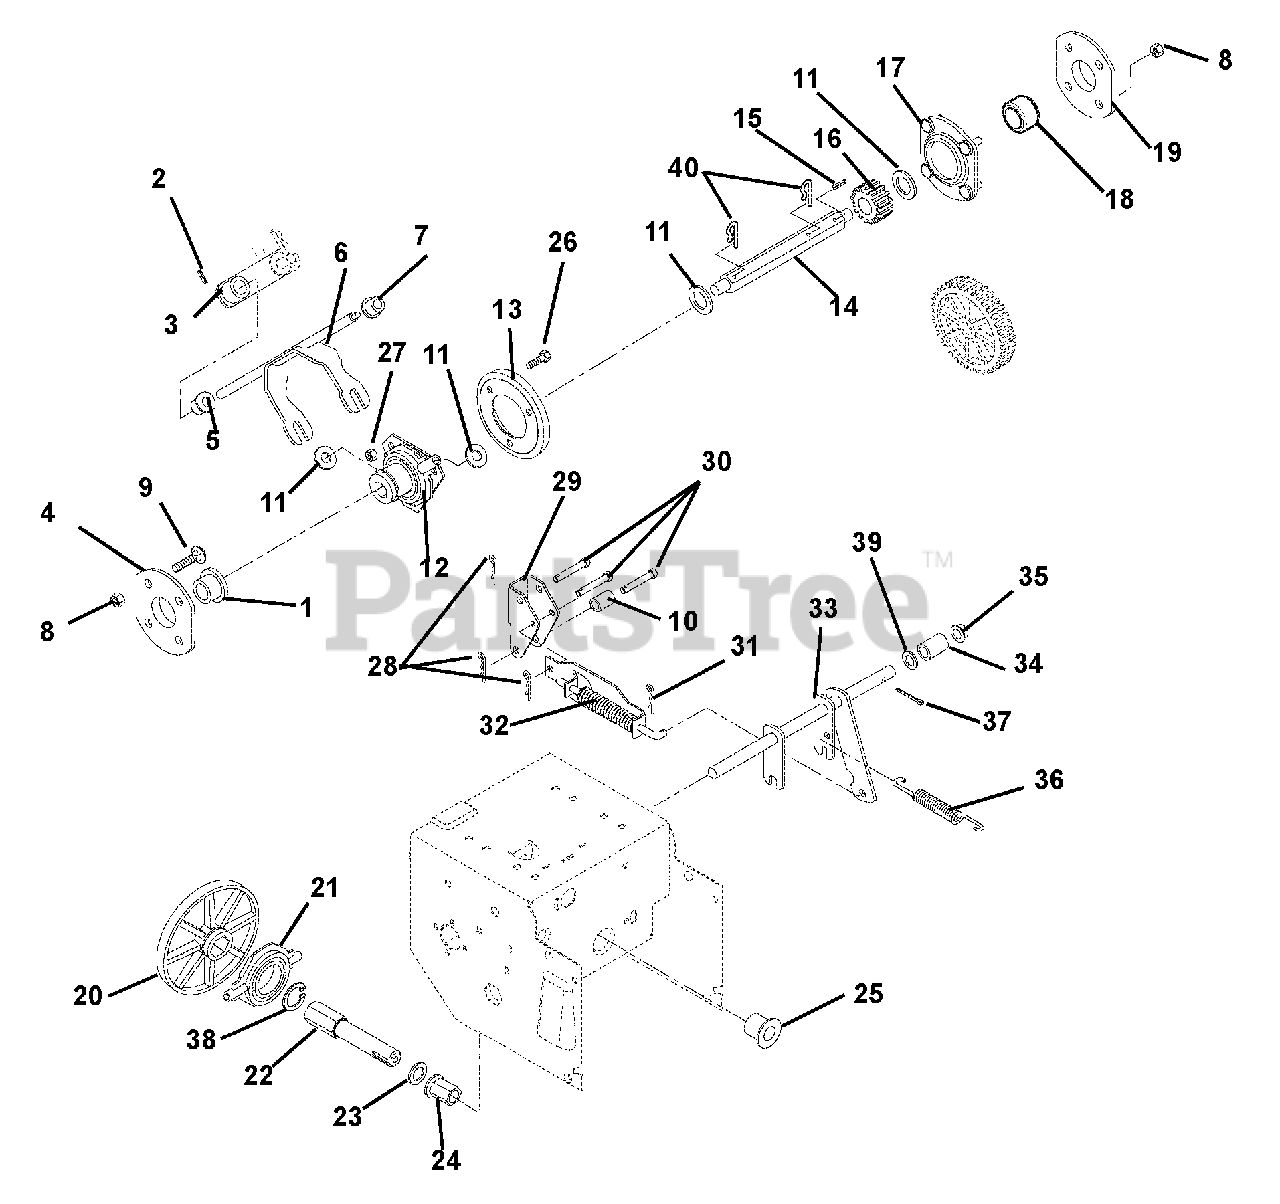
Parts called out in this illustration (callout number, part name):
1	BSHG-FLG .500X.750X.625X.937
2	PIN-ROLL .156X.88
3	WELDMENT, SPEED CONTROL ARM
4	FLANGE AND BUSHING
5	BSHG-FLG .500X.625X.500X.750
6	FORK-SPEED
7	BSHG-FLG .325X.444X.440X.560
8	NUT-LK-DUAL FACE 10-24 YWZC
9	BLT-RDHDSQSHK #10-24X.38 GR2YW
10	SPACER .325 X.625 X.455
11	WSHR-FL-STL .505X1.00X.062YWZC
12	SHIFT CARRIER
13	DISC, FRICTION - 730 MAT'L
14	SHAFT, HEX
15	PIN-ROLL .125X.88
17	BEARING FLANGE
18	BRG-BALL .437X1.375X.437
19	BEARING FLANGE
20	FRICTION PLATE
21	BEARING ASSEMBLY
22	SHAFT, SPINDLE - COMPACT SNOW
23	WSHR-THRST .625 X 1.0 X .03
24	BSHG-FLG .625X.875X1.750X1.188
25	BSHG-FLG .875X1.25X.75X1.50HX
26	@BLT-HEX .25-20X.50 GR5 YWZC
27	@NUT-LK-CTR .25-20 YWZC
28	PIN-HAIR INT .06X.18X.77
29	BRACKET, TRACTION ARM
30	PIN,CLEVIS .243/.248 X 1.38 YZ
31	PIN-HAIR INT .08X.18X1.18 YWZC
32	TRACTION CLUTCH ASSY
33	CLUTCH FORK
34	SPACER .504X.748X.321
35	CAP, .50 ROD YWZC
36	SG-TENS .063X.44X1.56
37	@PIN-CTR .12X1.00 EXTPRSQCT YZ
38	RG-RTNG-EXT 1.250X.050
39	@WSHR-FL-STL.531X1.06X.095YWZC
40	PIN, SPRING CLIP
